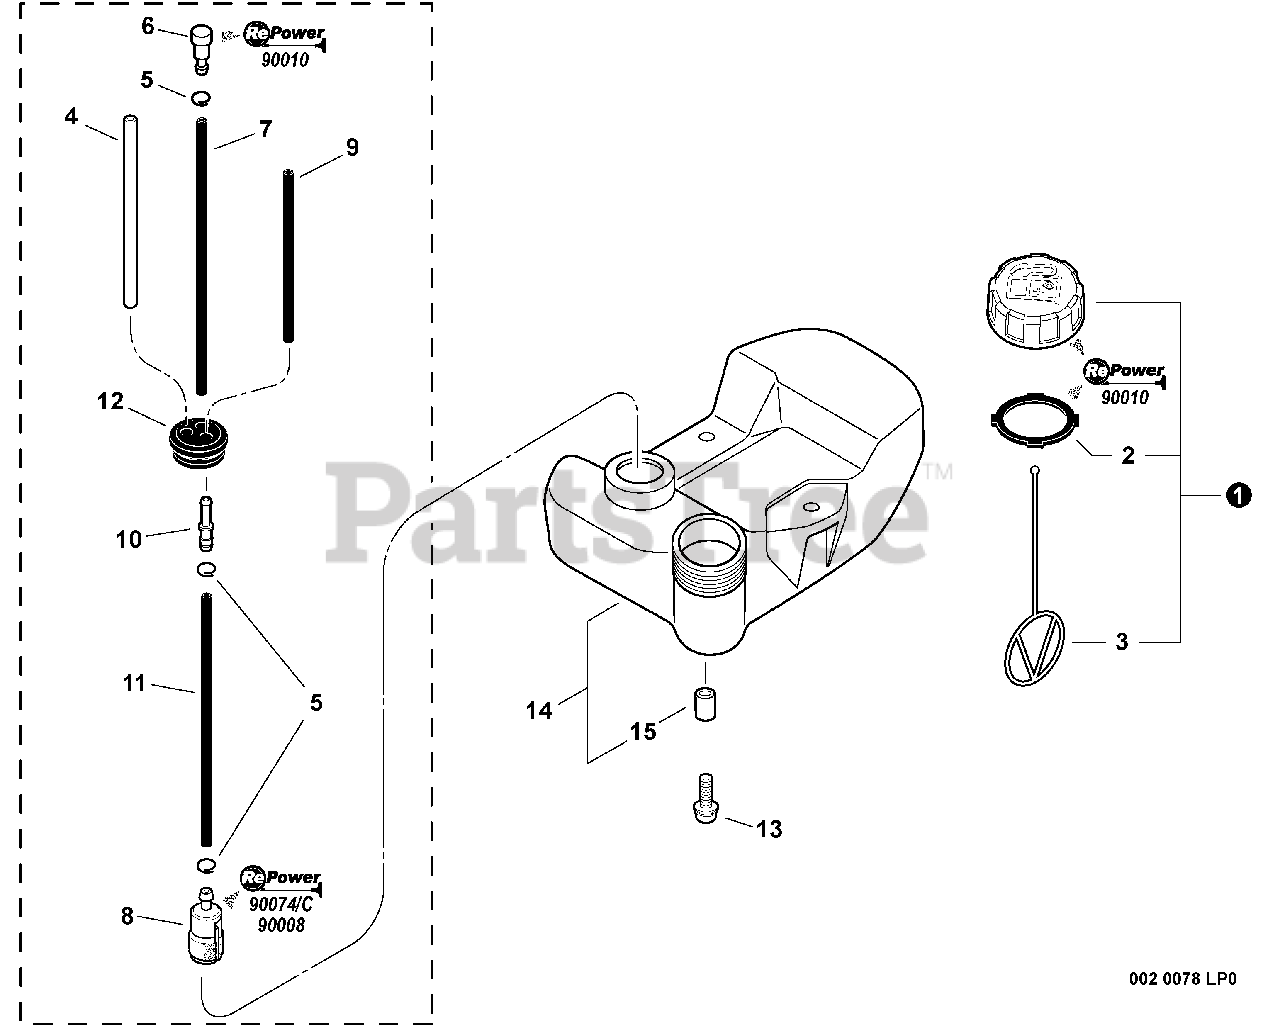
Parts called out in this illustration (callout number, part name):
1	CAP ASSY, FUEL
2	GASKET, FUEL CAP
3	CONNECTOR, CAP L= 100 MM
4	PIPE, FUEL 3×6×80 CLEAR
6	VENT ASSY
7	PIPE 3×6×115 BLACK
8	FILTER, FUEL
9	PIPE, FUEL - 3×5×67 - BLACK
10	CONNECTOR, PIPE Ø5ר3.5
11	PIPE, FUEL 3×6×110
12	GROMMET, FUEL
13	SCREW 5×16
14	TANK ASSY, FUEL
15	SPACER 6.2×7.8×6
16	TUNE-UP KIT - REPOWER
17	FILTER KIT - REPOWER
18	CAP/VENT KIT - REPOWER
